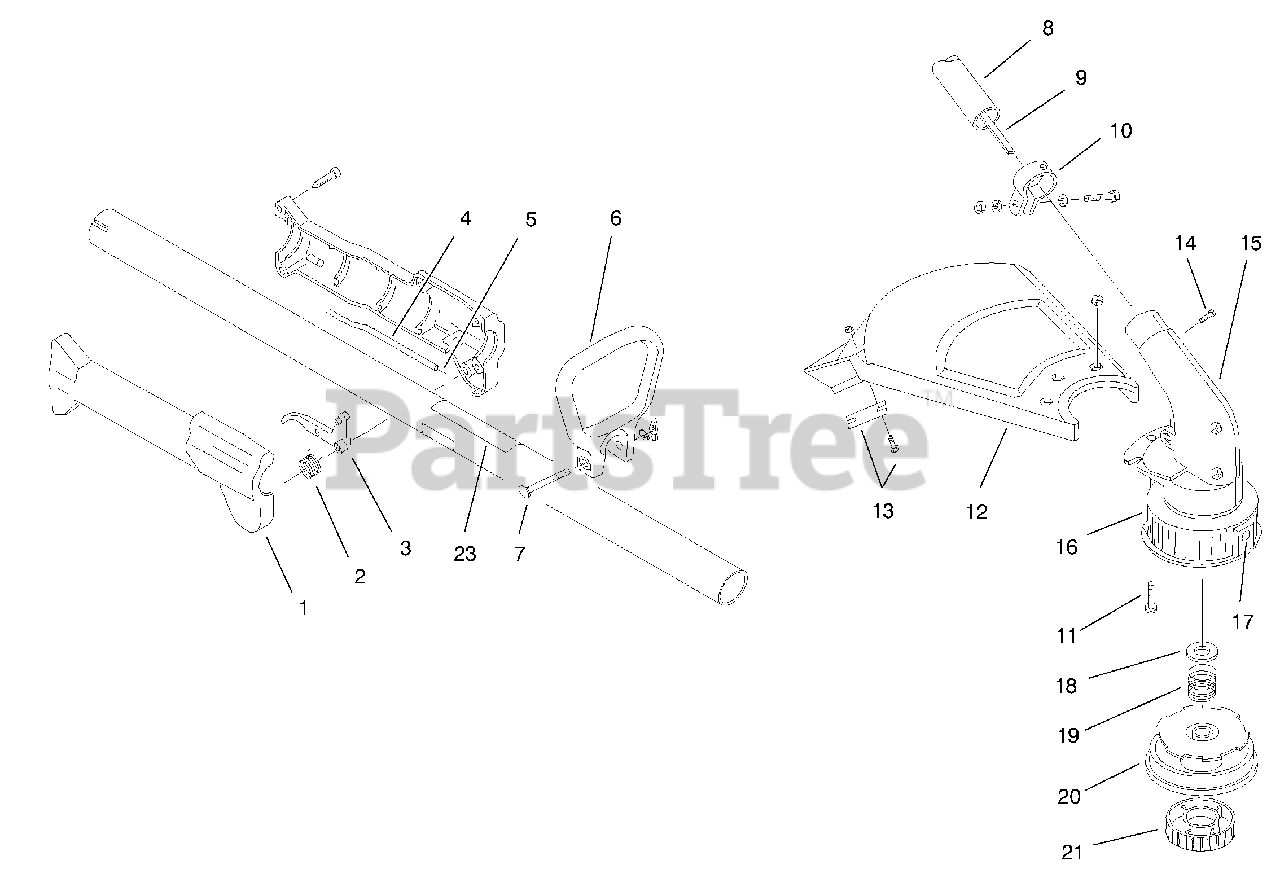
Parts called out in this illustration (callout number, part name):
1	Throttle Housing & Trigger Asm.
2	Throttle Trigger Spring
3	Throttle Trigger
4	Throttle Cable Housing Asm.
5	Throttle Cable
6	D-Handle
7	D-Handle Hardware Asm.
8	Drive Shaft Housing Asm.
9	Flexible Drive Shaft
10	Lower Clamp Asm.
11	Guard Mounting Screw Asm.
12	Guard and Blade Asm.
13	Blade Asm.
14	Anti-Rotation Screw
15	Gearbox Asm.
16	Outer Spool and Eyelet Asm
18	Retainer
20	Inner Reel
21	Bump Head Knob Asm.
23	Decal-Safety Symbols
